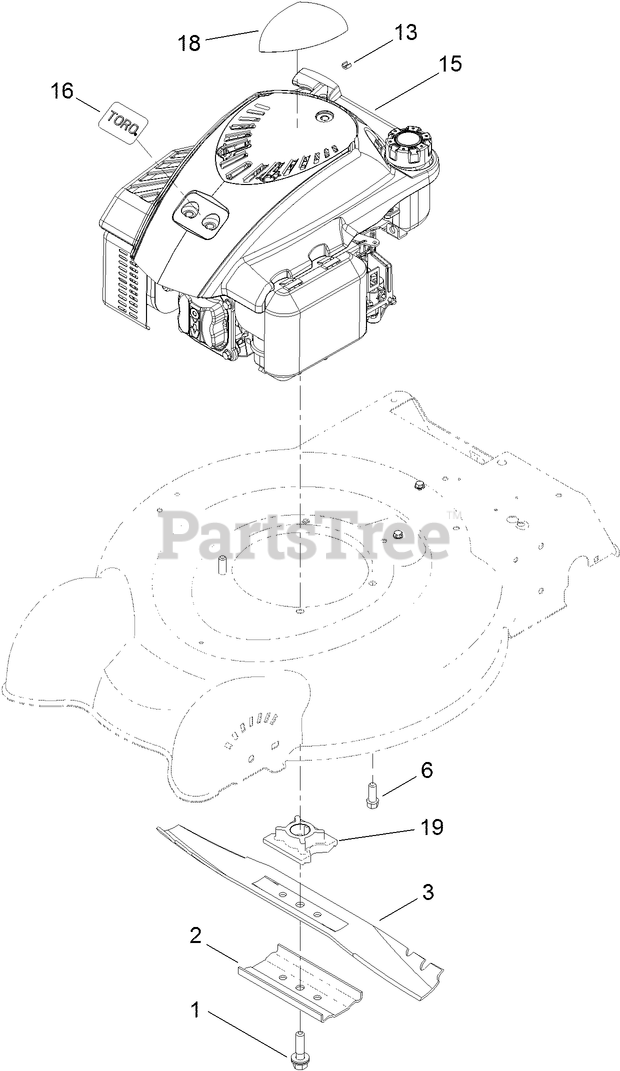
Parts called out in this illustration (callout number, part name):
2	SUPPORT-BLADE
6	SCREW-TAPTITE
13	STOP-ROPE
16	PLATE-LOGO, TORO
18	DECAL-SHROUD
19	RETAINER-BLADE
